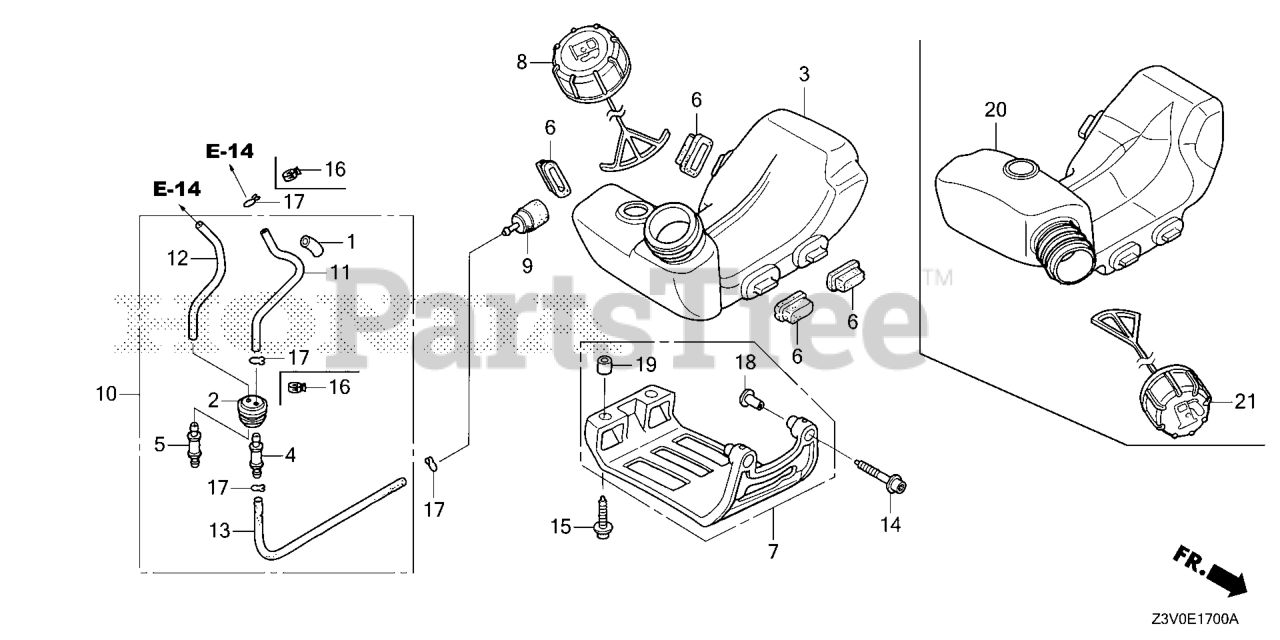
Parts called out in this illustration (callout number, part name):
1	PROTECTOR, TUBE
2	GROMMET, FUEL TUBE
3	TANK, FUEL
4	JOINT, FUEL TANK
6	RUBBER, TANK MOUNTING
8	CAP ASSY., FUEL TANK
9	FILTER, FUEL
10	GROMMET, FUEL TANK
11	TUBE, FUEL
12	TUBE, FUEL RETURN
13	TUBE A, FUEL
16	CLAMP, TUBE
17	CLIP, TUBE (B1 5)
